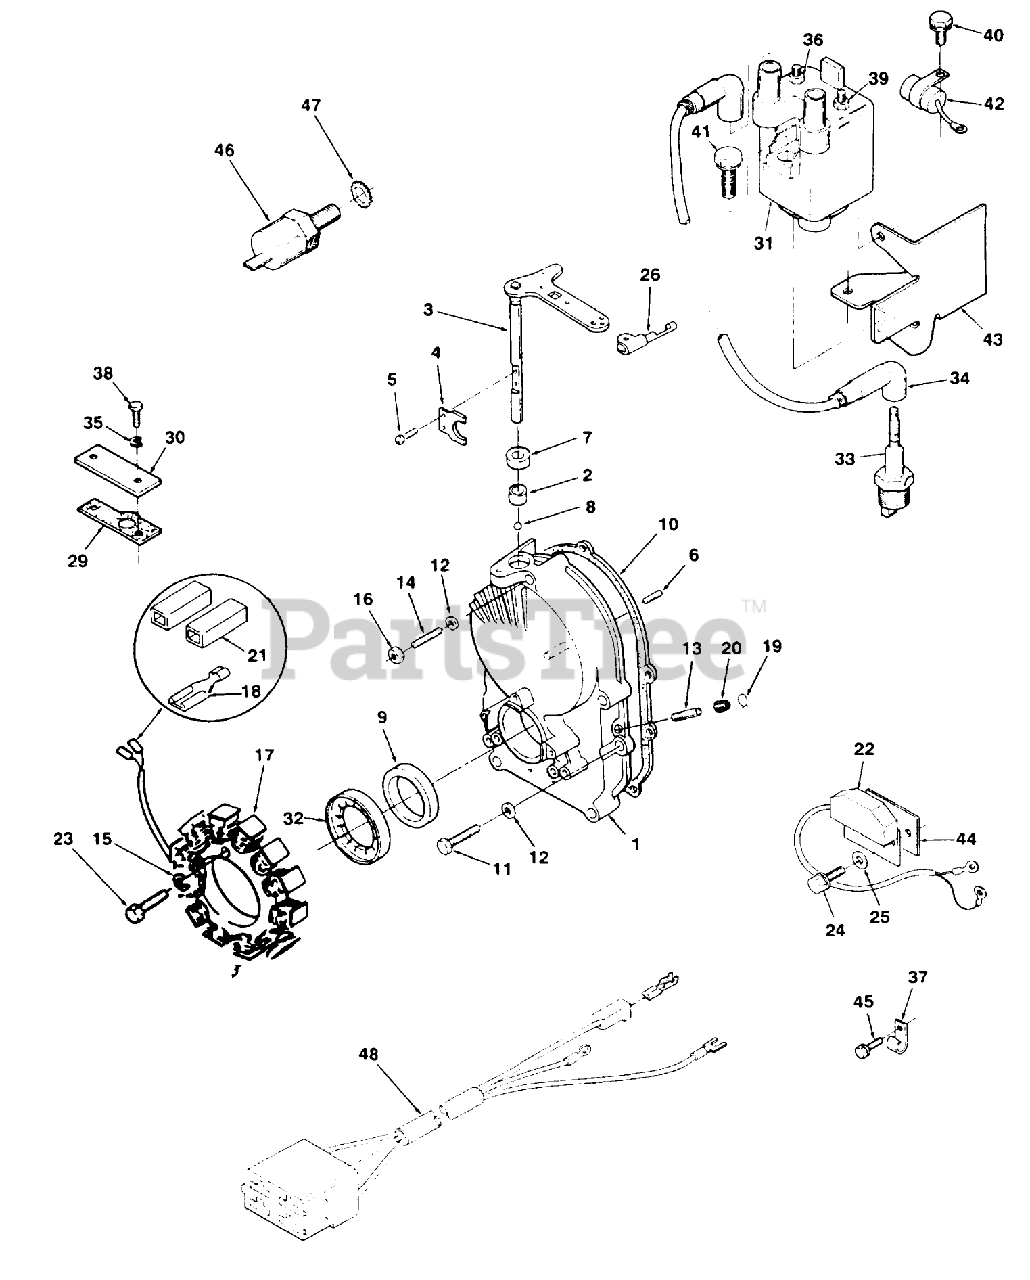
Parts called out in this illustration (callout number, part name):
1	Kit-Gearcase (Incl. Ref. #2 thru 9)
2	BEARING
3	SHAFT/ARM-GOVERNOR
5	SCREW-PAN HD
6	PIN-DOWEL
10	GEAR CASE MTG GASKET
11	HEX-HEAD CAP SCREW
12	WASHER
13	TUBE-PORT, VACUUM
14	STUD-GEAR COVER
15	WASHER-LOCK
16	NUT-GEAR COVER
17	KIT - STATOR
18	TERMINAL
19	CLAMP
20	CAP-FUEL OUTLET
21	BODY-TERM. CONNECTOR KIT
22	CONTROL-IGNITION
23	Screw-HH
24	Bolt
25	WASHER-LOCK
29	GASKET
30	PLATE-COVER
31	COIL-BATTERY IGNITION
32	ROTOR-IGNITION
33	SPARK PLUG
34	Wire-Plug
35	WASHER-FLAT
36	NUT-HEX FLANGE
37	CLIP-WIRE
38	SCREW - CAP HEX HEAD
39	NUT-HEX FLANGE
40	HEX HD CAPSCREW
41	SCREW-HH
42	CONDENSER
43	BRACKET - COIL MTG
44	INSULATOR-IGN MODULE
45	HEX-HEAD CAP SCREW
46	HIGH TEMPERATURE
47	WASHER-LOCK EXT TO
48	WIRE HARNESS
